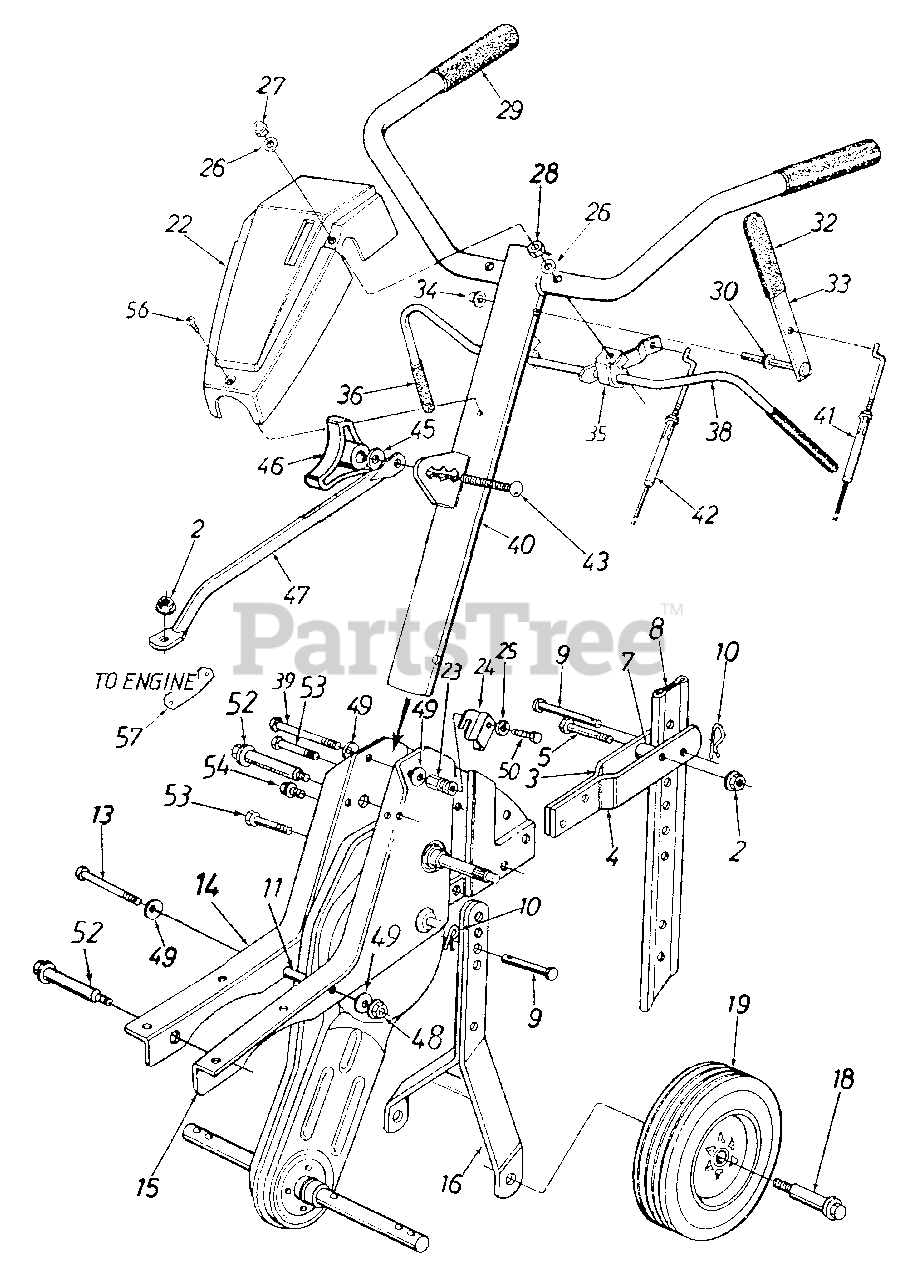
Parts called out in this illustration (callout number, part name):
2	Hex Flange L-Nut 5/16-18 Thd. (Gr. 5)
5	Hex Bolt 5/16-18 x 1.5" Lg.
7	Spacer .32" I.D. x .75" O.D.
9	Clevis Pin .375" I.D. x 1.62" Lg.
10	Internal Cotter Pin
11	Spacer .326" I.D. x .47" O.D.
13	Hex Bolt 5/16-18 x 2.75" Lg.
18	Shld. Bolt 3/8-16 Thd.
19	Wheel Ass'y. 8" x 1.75"
22	Handle Cover w/Reverse
23	Spec. Hex Nut
25	L-Wash. 5/16" I.D.
26	Fl-Wash. .266" I.D. x .625" O.D.
27	Hex L-Stop Nut 1/4-20 Thd.
28	Hex Nut 1/4-20 Thd.
29	Grip-Handle
30	Fl-Wash. .344" I.D. x .62" O.D.
32	Grip-Reverse Lever
34	Cap Speed Nut
35	Clutch Handle Holder
36	Grip-Clutch
39	Hex Bolt 5/16-18 x 3" Lg.
42	Clutch Control Cable-Forward
43	Carr. Bolt 5/16-18 x 1" Lg. (Special)
45	Wash. Bell. .340" ID x .872" OD
46	Hand Knob
49	Bell-Wash. .345" I.D. x .88" O.D.
50	Hex Bolt 5/16-18 x .75" Lg. (Gr. 5)
52	Shld. Bolt
53	Hex Wash. Hd. TT-Tap Scr. 5/16-18 x .62" Lg.
54	Hex Wash Hd. TT-Tap Scr. 5/16-18 x 1" Lg.
56	Truss Mach. Scr. #10 x 1/2" Lg.
57	Engine Bracket
